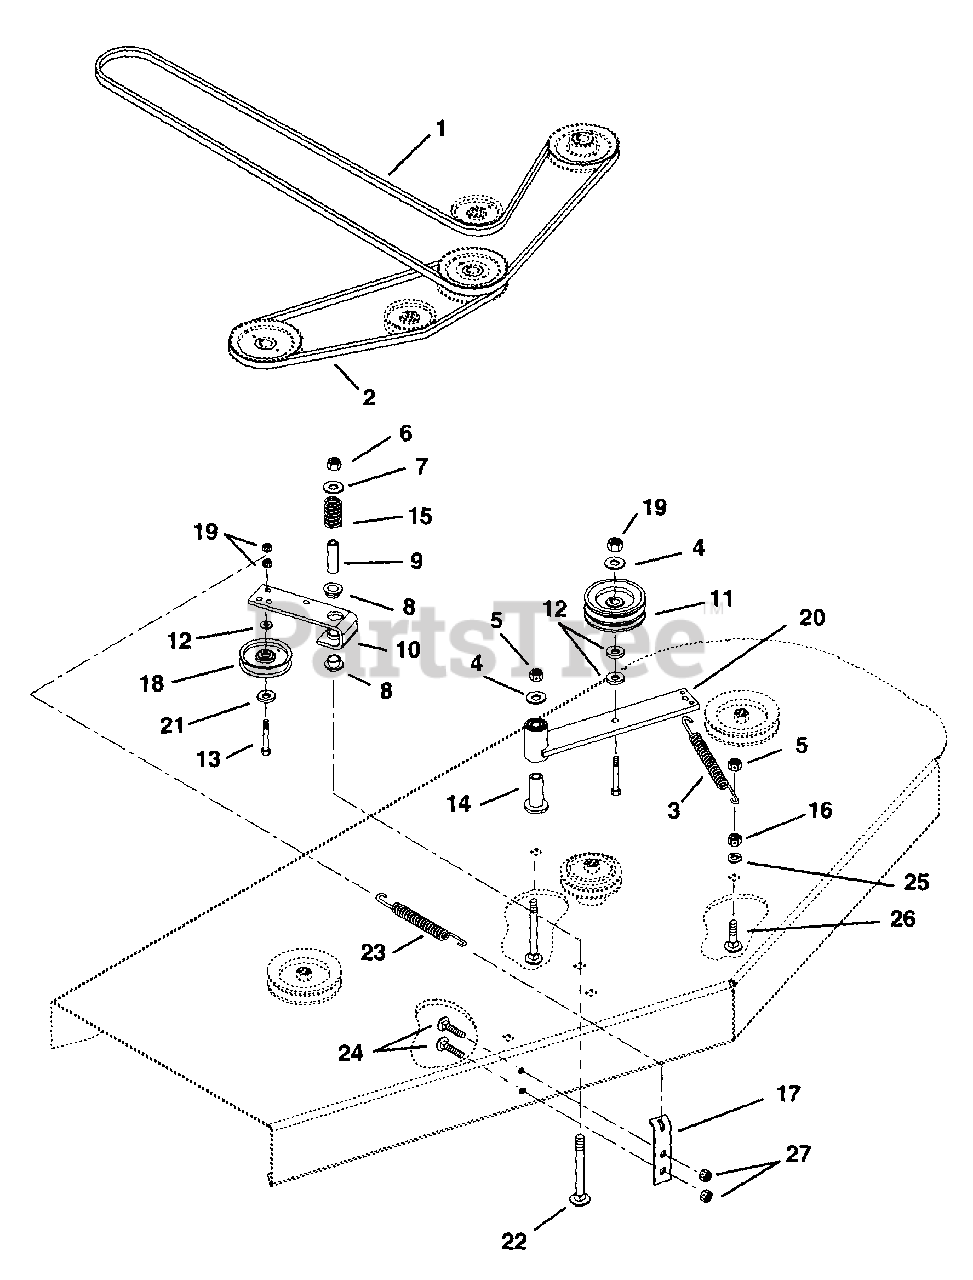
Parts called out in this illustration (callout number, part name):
1	V-Belt B-Section 60" Mower
1	V-Belt B-Section 50" Mower
2	V-Belt A-Section 60" Mower
2	V-Belt A-Section 50" Mower
3	Spring, Coil
4	Washer-Flat-Steel .406 x .812 x .065
5	Nut-Locking .38-16
6	Nut-Locking .50-13
7	Washer-Flat-Steel .531 x 1.250 x .100
8	Bushing-Flange .762 x 1.0 x .580 x 1.48
9	Spacer .560 x .750 x 2.437
10	Arm, Idler Pivot
11	Idler-Flat 4 x .38
12	Bushing .406 x .750 x .188
13	Bolt-Hex .38-16 x 2.25 Grade 5
14	Bearing, Pedestal
15	Spring-Compression .085 x .80 x 1.00
16	Nut-Hex .38-16
17	Anchor, Spring
18	Sheave, Idler
19	Nut-Locking-Ctr .38-16
20	Assembly, Idler Pivot Arm
21	Washer-Flat-Steel .375 x 1.125 x .065
22	Bolt-Round Head Square Neck .50-16 x 3.50
23	Spring, Ext.
24	Bolt-Round Head Square Neck .31-18 x .75 Gr. 5
25	Washer-Locking .38 x .875 x .160
26	Bolt-Round Head Square Neck .38-16 x 1.75
27	Nut-Locking-Ctr .31-18
